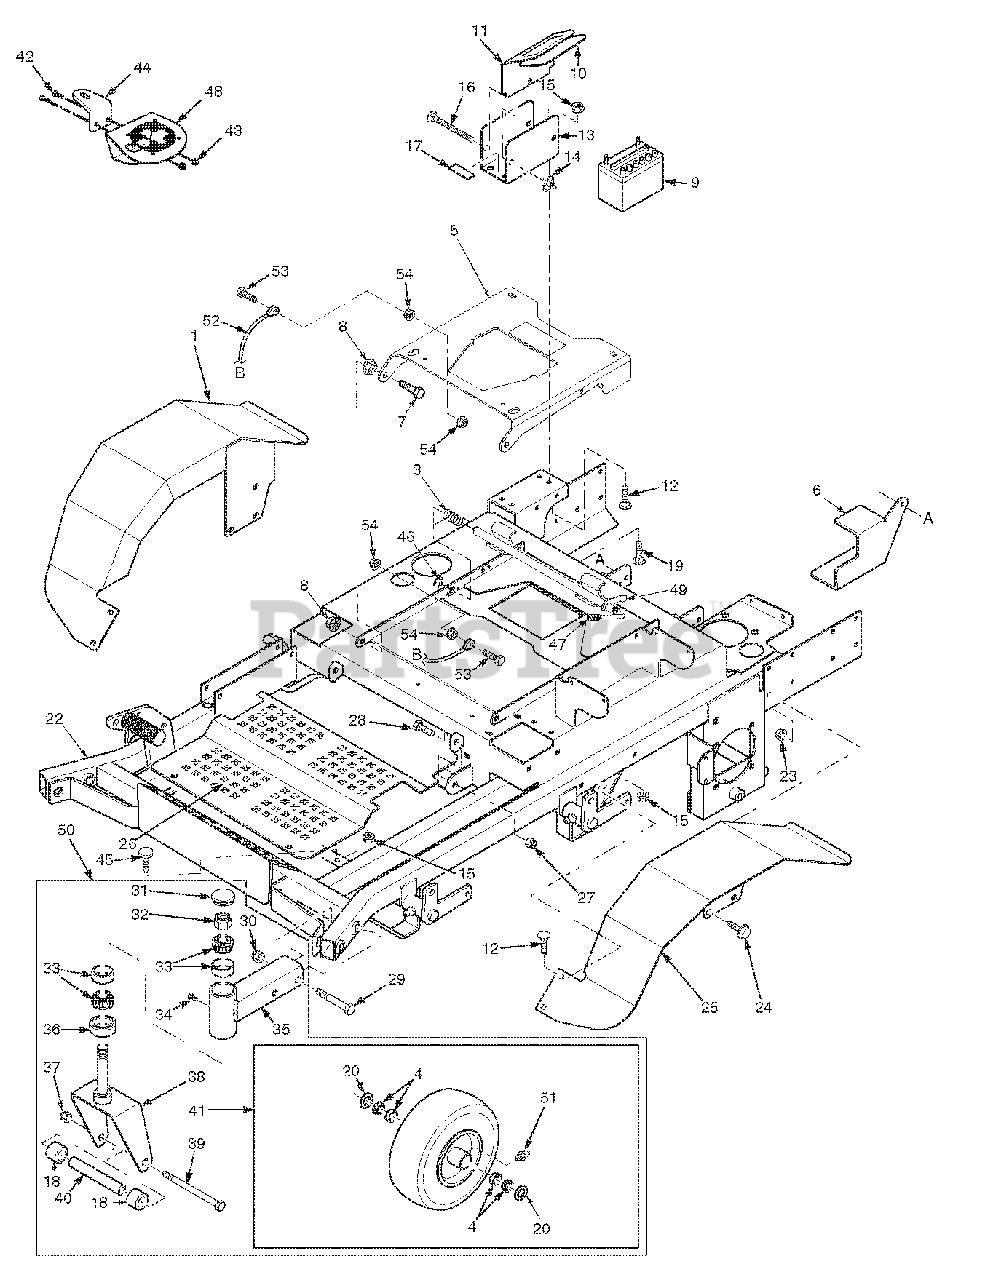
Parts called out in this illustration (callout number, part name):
1	Fender Weldment, RH
2	Bolt, Hex Head, 5/16-18 x 1, Zinc
3	Spring, Seat Latch
4	Bearing w/ Race
5	Seat Plate w/Decal
6	Guard, Fuel Line
7	Bolt, Hex Head 7/16-14 x 1-3/4"
8	Nut, 7/16-14 Serrated Flange
9	Battery (not avail. through Scag)
10	Pad, Battery Cover
11	Cover, Battery
12	Bolt, Carriage 5/16-18 x 3/4"
13	Plate, Battery Box
14	Wing Nut, 1/4-20 x 3/4"
15	Nut, Hex Serrated Flange 5/16-18
16	Bolt, Carriage 1/4-20 x 6"
17	Rubber Pad
18	Spacer, Caster Wheel
19	Bolt, Carriage 5/16-18 x 1"
21	Locknut, 3/8-16, Elast. Stop
22	Main Frame w/Decals
23	Nut, Hex Serrated Flange 3/8-16
24	Screw, Hex Serrated Flange 3/8-16 x 1"
25	Fender Weldment, LH
26	Foot Plate
27	Nut, Hex Elastic Stop 3/8-16
28	Bolt, Hex Head 3/8-16 x 1"
29	Bolt, Hex Head 5/8-11 x 4"
30	Nut, Hex Elastic Stop 5/8-11
31	Cap, Grease
32	Nut, Hex Elastic Stop 1.0-14
33	Bearing W/Race
34	Plug, 1/4-28 THD Form
35	Extention Weldment, Caster 52V (LH)
35	Extention Weldment, Caster 52V (RH)
35	Extention Weldment, Caster 61V (LH)
35	Extention Weldment, Caster 61V (RH)
35	Extention Weldment, Caster 72VS (LH)
35	Extention Weldment, Caster 72VS (RH)
36	Seal, 2.00" OD. x 1.625" Bore
37	Nut, Hex Elastic Stop 1/2-13
38	Yoke Weldment, Caster (52V)
38	Yoke Weldment, Caster (61V & 72A/VS)
39	Bolt, Hex Head 1/2-13 x 7-1/2" (52V)
39	Bolt, Hex Head 1/2-13 x 9-1/2" (61V & 72A/VS)
40	Sleeve, Caster Wheel (52V)
40	Sleeve, Caster Wheel (61V, 72A/VS)
41	Wheel Assy, 52V (Incl. items 20, 54, 55)
41	Wheel Assy, 61V, 72V (Incl. 20, 54, 55)
42	Bolt, Hex Head 1/4-20 x 3/4"
43	Bolt, Hex Head 1/4-20 x 3/4"
44	Mounting Bracket, STT Cup Holder
45	Bumper, Rubber
46	Retaining Ring, .625" Ext. "E"
47	Grip, Seat Latch
48	Cup Holder Assembly
49	Lever Assembly, Seat Release
50	Caster Wheel Assembly 52V (LH)
50	Caster Wheel Assembly 52V (RH)
50	Caster Wheel Assembly 61V (LH)
50	Caster Wheel Assembly 61V (RH)
50	Caster Wheel Assembly 72VS (LH)
50	Caster Wheel Assembly 72VS (RH)
51	Grease Fitting
52	Cable, Seat Stop
53	Bolt, Hex Head 1/4-20 x 1-1/4"
54	Nut, Serrated Flange 1/4-20
